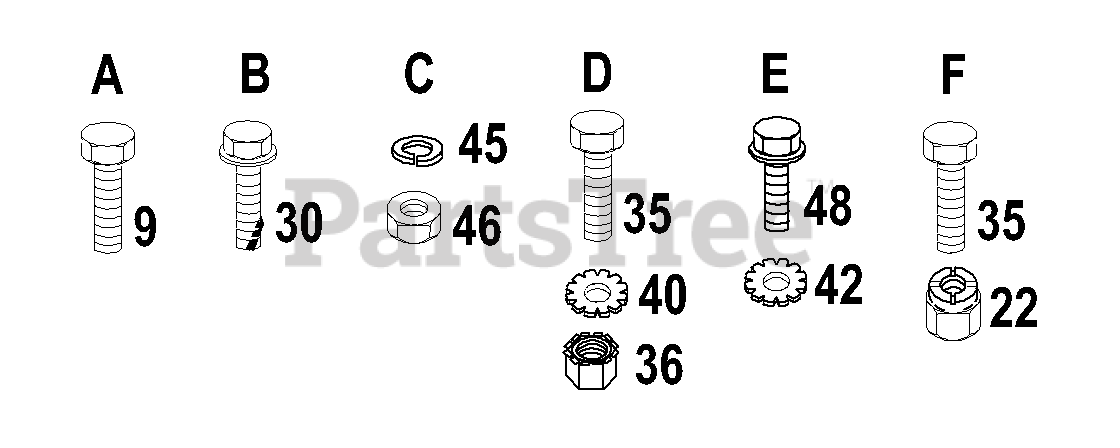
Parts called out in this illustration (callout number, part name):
9	Screw #10-24 x 1/2
22	Nut, Crownlock 1/4-20
30	Screw, Hex, Tap #10-24 UNC
35	Bolt, Hex 1/4-20 x 1/2 Grade 5
36	Nut, Hex, Keps 1/4-20
40	Washer, Lock, External Tooth 1/4
42	Washer, Lock, External Tooth 3/8
45	Washer, Lock 1/4
46	Nut, Hex, Jam 1/4-20
48	Screw, Hex Washer Thrd. Cut 1/4-20 x 1/2
